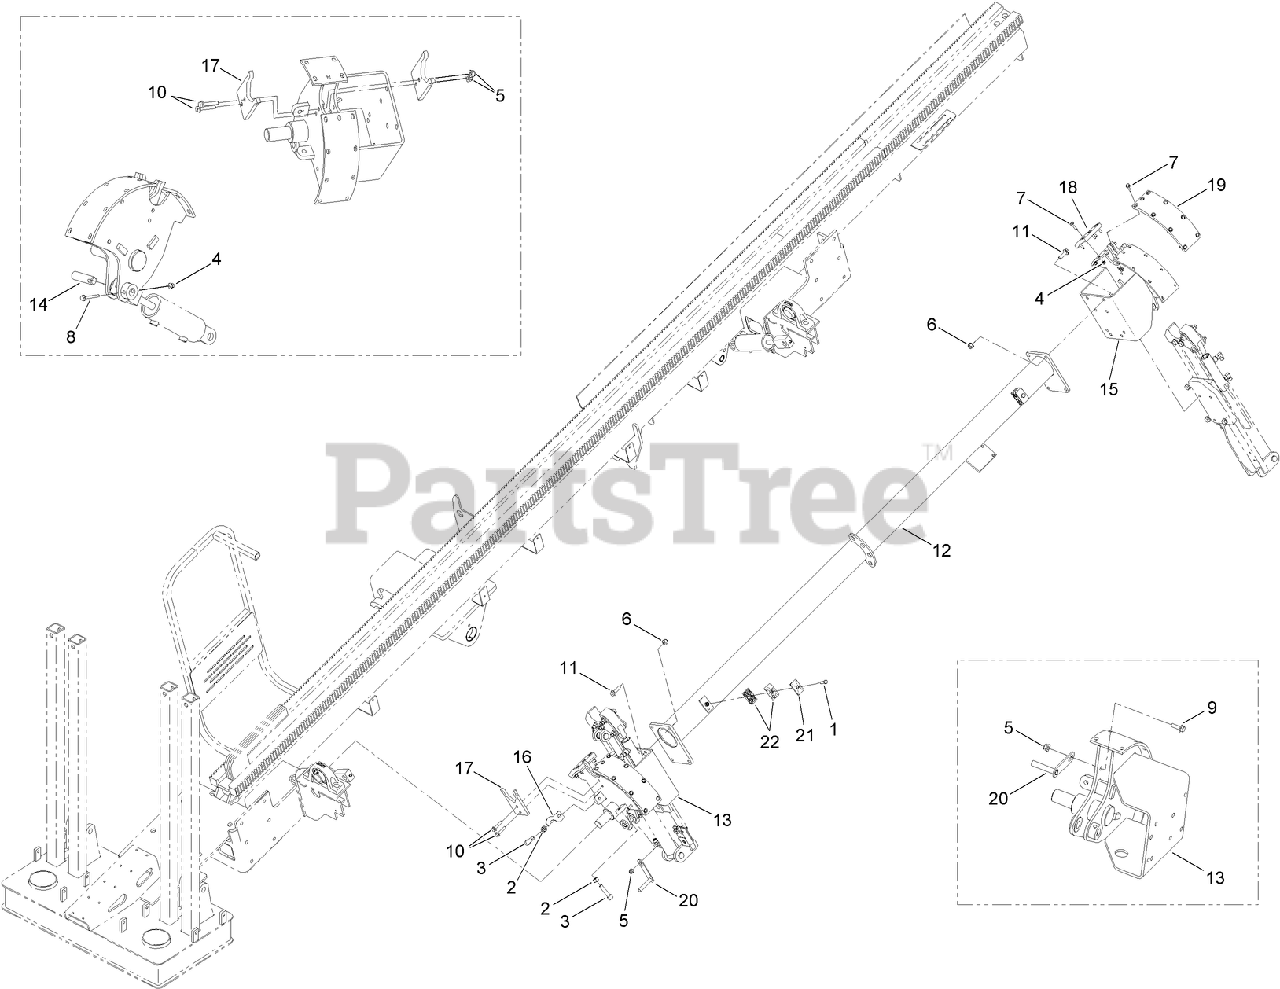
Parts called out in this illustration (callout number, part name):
1	SCREW-HH
3	SCREW-HSFH
4	NUT-FLANGE, NI
5	NUT-LOCK, HHF
6	NUT-LOCK, NI
7	SCREW-HHF
8	SCREW-HHF
9	SCREW-HHF
10	SCREW-HHF
11	SCREW-HHF
12	SPINE-LOADER, ROD
14	PIN-STRAIGHT
15	CAM
16	PLATE-POINTER
17	PLATE-GUIDE, PIPE
18	PAD-WEAR, ROD LOADER
19	PAD-WEAR, ROD LOADER
20	FLAG-SENSOR
21	PLATE-COVER, TWIN
22	CLAMP-HALF (SET OF 2)
